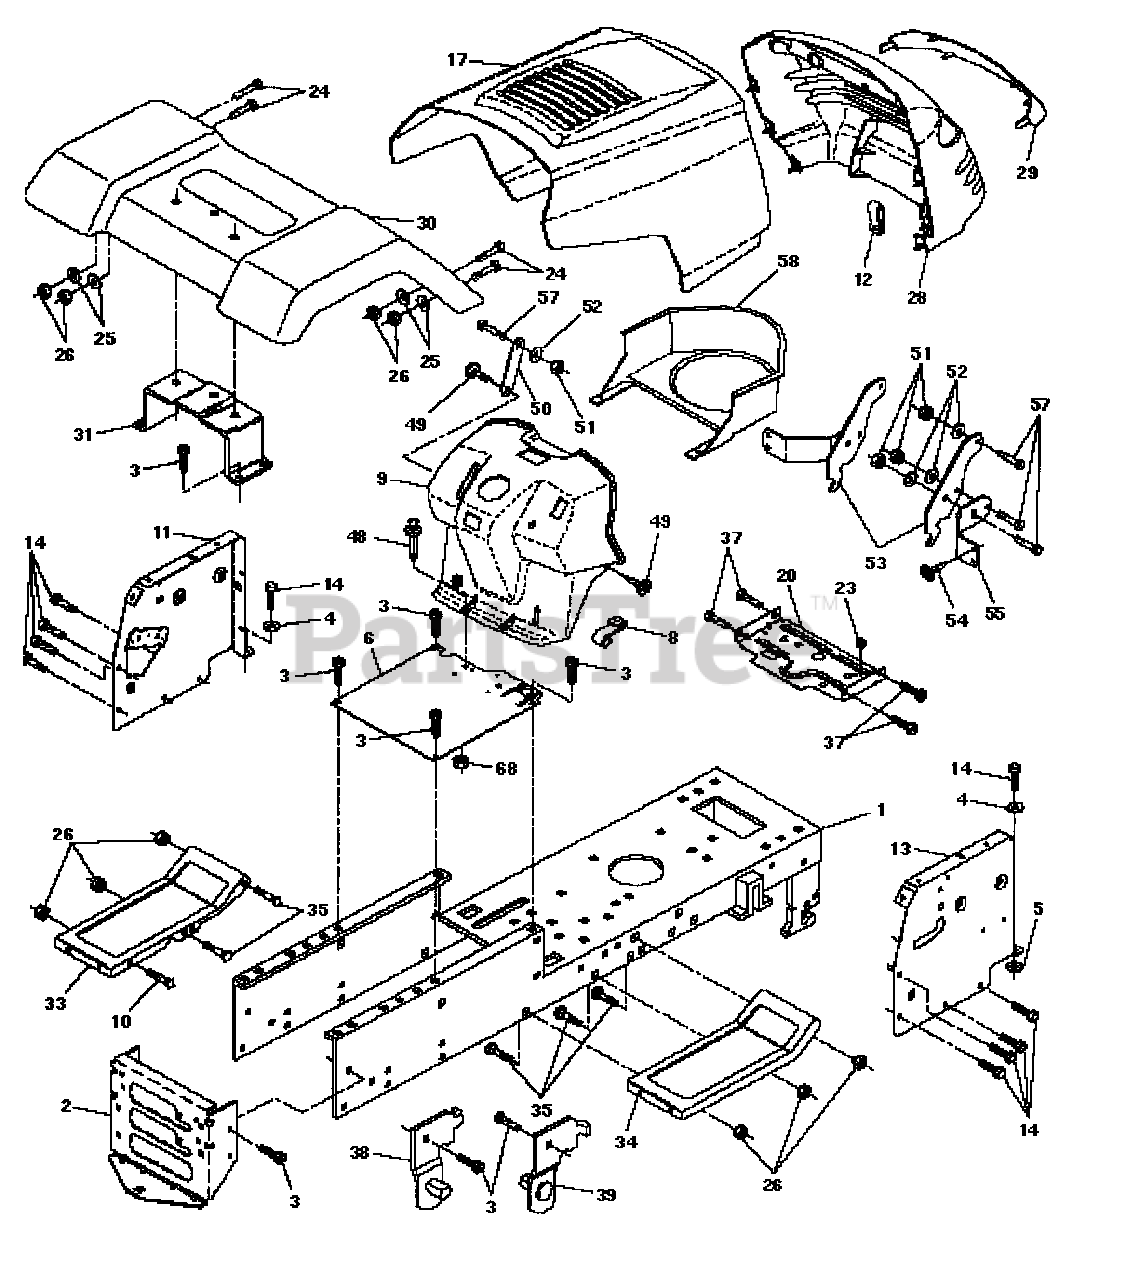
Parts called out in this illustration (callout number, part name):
1	Chassis Weldment 11ga
2	Drawbar, Stretch
3	Screw Thdrol 3/8-16x3/4 Ty-tt
4	Washer 13/32 x 3/4 x 16 Ga.
5	Washer Lock Ext. Tooth 3/8
6	Saddle LT Fender Shift
8	Clip Insulator .406 Mtg Hole
9	Dash Private Label
10	Bolt Carriage 3/8-16 x 1
11	Panel Pnt Dash Lh
12	Clip Tinnerman Grille Private Label
13	Panel Dash Rh Weldment
14	Screw Thdrol 3/8-16x1/2 Ty-tt
17	Hood Paint Steel Private Label
20	Support Battery
24	Bolt Fin Hex 3/8-16unc X1
25	Washer 13/32 X 13/16 X 12 Ga
26	Nut Lock 3/8-16 Unc
28	Grille Private Label
29	Lens Grille Private Label
30	Fender Pnt
31	Bracket Pnt Fender
33	Footrest Pnt Lh
34	Footrest Pnt Rh
35	Bolt Rdhd Sht Sqnk 3/8-16 X3/4
37	Screw Thdrol 5/16-18 X3/4
38	Bracket, Asm. Pivot, L.H., Mower Rear
39	Bracket, Asm. Pivot, R.H., Mower Rear
48	Rivet Push
49	Screw Hexwsh. Thdrol 1/4-20 x 3/4
51	Nut Lock Hex W/Ins 1/4-20
52	Washer 9/32 x 7/8 x 16 Ga.
53	Hinge Pickoff Hood
54	Screw Lock Spider #8 x 7/8
55	Bracket, Grill
57	Screw Hex 1/4-20 x 3/4
58	Air Duct P/L
68	Nut Keps Hex 1/4-20 UNC
